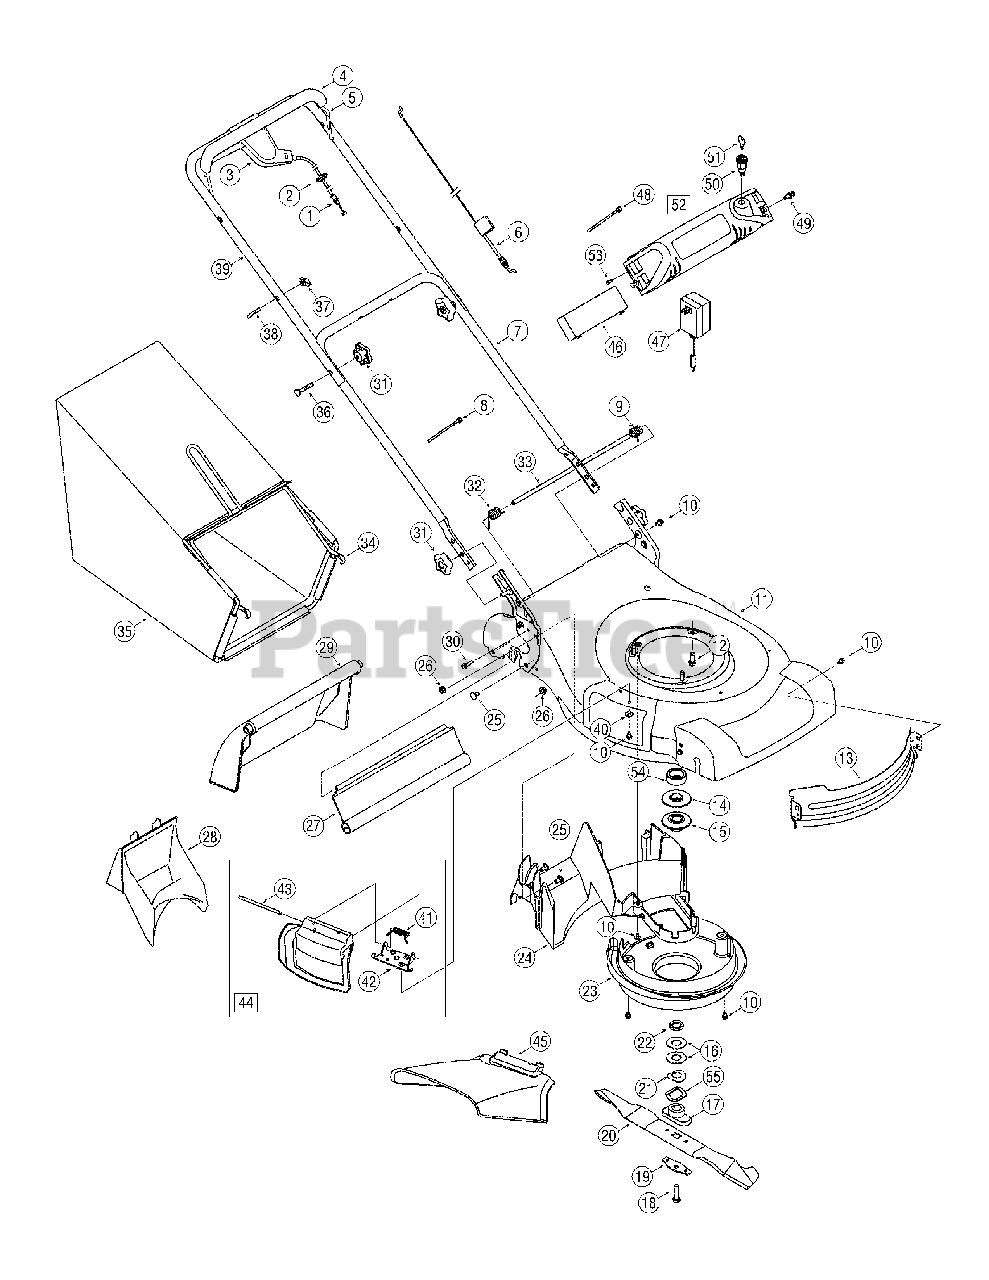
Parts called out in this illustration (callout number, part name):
1	Drive Cable
2	Rubber Grommet
3	Drive Control Assembly
4	Bail Cover
5	Blade Control
6	Control Cable
8	Cable Tie
9	Torsion Spring, LH
10	TT Screw, 1/4-20 x .62
12	TT Screw, 3/8-16 x 1.00
13	Front Deck Baffle
14	Upper Engine Pulley
15	Lower Engine Pulley
16	Flat Wash., .885 x 1.850 x .060
17	Blade Adapter
18	Screw, 3/8-24 x 1.50
19	Blade Bell Support
20	21" Mulching Blade
21	Sprg Washer, .890 x 1.70 x .048
22	Sleeve Spacer, .88 x 1.13 x .12
22	Slv. Spcr., 25mm x 1.375 x .375
23	Engine Baffle
24	Deck Baffle
25	Carriage Bolt, 5/16-18 x .62
25	Hex Cap Screw, 5/16-18 x .625 GR5
26	Flange Lock Nut, 5/16-18
27	Trailshield
27	Screw, Hex Washer Hd. Tapp #10-16 x .375
28	Mulch Plug
29	Rear Door
30	Screw, 1/4-15 x 1.00
31	Star Knob
32	Torsion Spring, RH
33	Door Pivot Rod
34	Grass Catcher Frame
35	Grass Catcher - Gray
35	Grass Catcher - Black
36	Carriage Bolt, 5/16-18 x 2.00
37	Wing Nut
38	Eye Bolt
41	Torsion Spring
42	Chute Deflector Adapter
43	Hinge Pin
44	Mulch Plug Assembly
45	Side Discharge Chute
46	12 Volt Battery
47	Battery Charger
48	Cable Tie
49	Rivet
50	Key Switch
52	Electric Starter Harness Ass’y.
53	Screw, #10-16 x .750
54	Sleeve Spacer
55	Washer, Wave, 1.5 x 1.0 x .029
